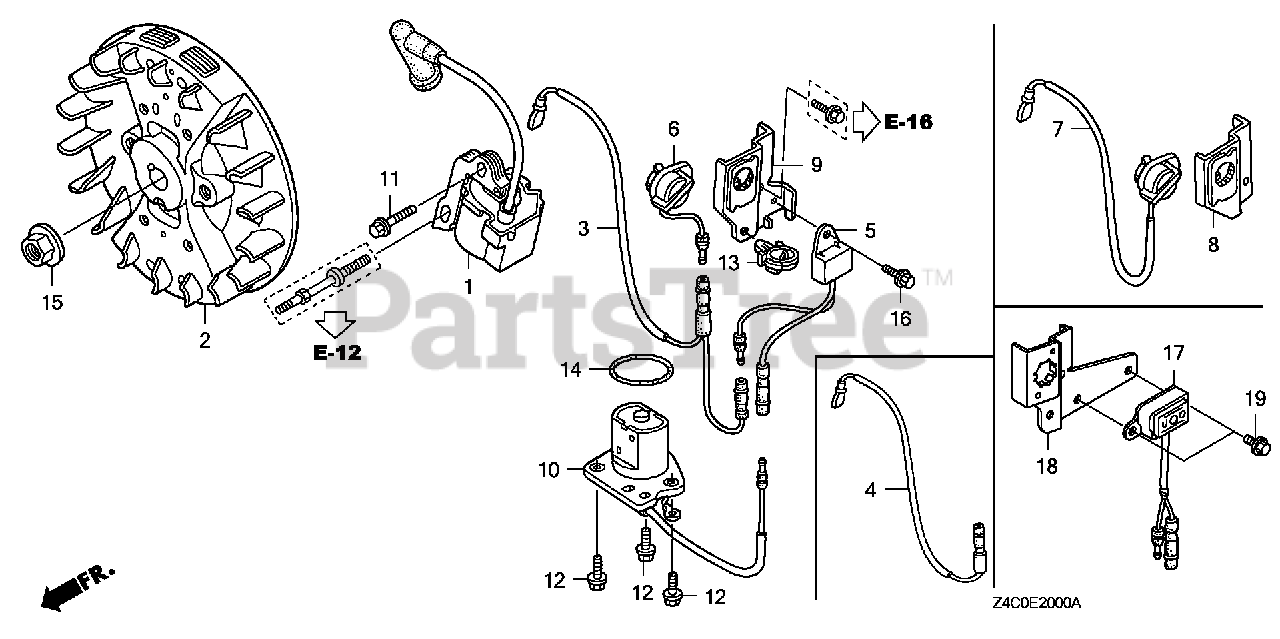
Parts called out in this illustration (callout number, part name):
1	COIL ASSY., IGNITION
3	WIRE, STOP SWITCH
5	ALERT UNIT, OIL
6	SWITCH ASSY., ENGINE STOP
9	BRACKET, STOP SWITCH
10	SWITCH ASSY., OIL LEVEL
11	BOLT, FLANGE (5X20)
12	BOLT, FLANGE (5X14)
13	CLIP, HARNESS
14	O-RING (34.6X2.5)
15	NUT, FLANGE (10MM)
16	BOLT, FLANGE (6X8)
